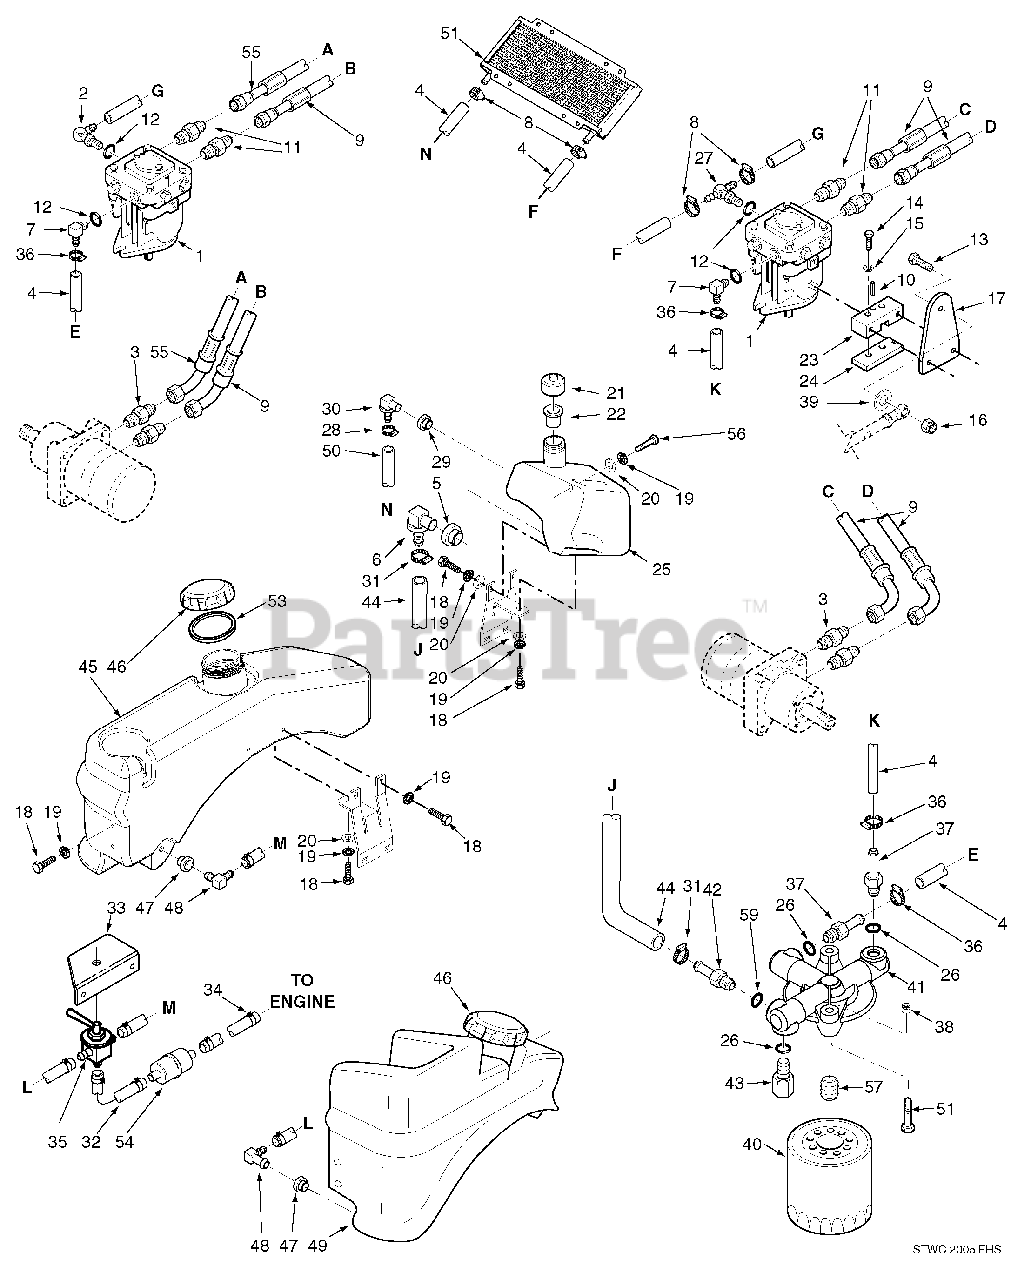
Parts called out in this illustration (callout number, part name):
1	Pump, BDP-10A-316 (LH)
2	Elbow, 90 Degree 9/16" O-Ring x 3/8" Hose
3	Fitting, 1/2" JIC x 5/8" O-Ring
4	Hose, 3/8" Pushlock (Specify length)
5	Bushing
6	Fitting
7	Elbow, 90 Degree 9/16" O-Ring x 3/8" Hose
8	Hose Clamp, .69" Dia.
9	Hose Assembly
10	Roll Pin
11	Fitting, 1/2" JIC x 1/2" O-Ring
12	O-Ring
13	Bolt, Hex Hd. 3/8-16 x 1-1/2"
14	Bolt, Hex Hd. 1/4-20 x 1-1/4"
15	Lockwasher
16	Nut, Elastic Stop 3/8-16
17	Control Lever
18	Bolt, Hex Hd. 5/16-18 x 3/4"
19	Lockwasher, 5/16"
20	Flatwasher, 5/16 (.375 x .875 x .083")
21	Cap, Hydraulic Tank
22	Insert, Filler Neck
23	Control Block
24	Clamp Plate
25	Hydraulic Tank Assembly w/Fittings
26	O-Ring
27	Tee Fitting, O-Ring to Barb
28	Clamp, .69" Max. / .25" Min. Dia.
29	Bushing
30	Elbow, 0.38" Hose
32	Fuel Hose, 1/4" ID Non-Perm.
33	Bracket Fuel Valve
34	Clamp, Fuel Hose 1/4" Hose ID
35	Valve, Fuel Shutoff
36	Clamp, .69" Max. / .25" Min. Dia.
37	Fitting, 9/16" O-Ring x 3/8" Hose
38	Nut, Serr. Flng. 5/16-18
39	Flatwasher, 3/8 (.391 x .938 x .105")
40	Oil Filter
41	Filter Head Assembly
42	Fitting, 3/4" O-Ring x 3/8" Hose
43	Plug, 9/16-18 O-Ring
44	Hose, Filter Inlet
45	Fuel Tank RH
46	Cap, Fuel Tank
47	Tank Bushing
48	Elbow, 90 Degree w/Screen
49	Fuel Tank LH
50	Hose, 3/8 Pushlock 15" Long
51	Cooler, Transmission
52	Screw, 1/4-20 x 2"
53	Gasket, Gas Tank Cap
54	Fuel Filter
55	Hose Assembly
56	Bolt, Hex Hd. 5/16-18 x 1-1/2"
57	Nipple, Oil Filter 1.0-12 UNF-2A x 1-1/4"
58	Bolt, Hex Hd. 5/16-18 x 2"
59	O-Ring, 3/4"
